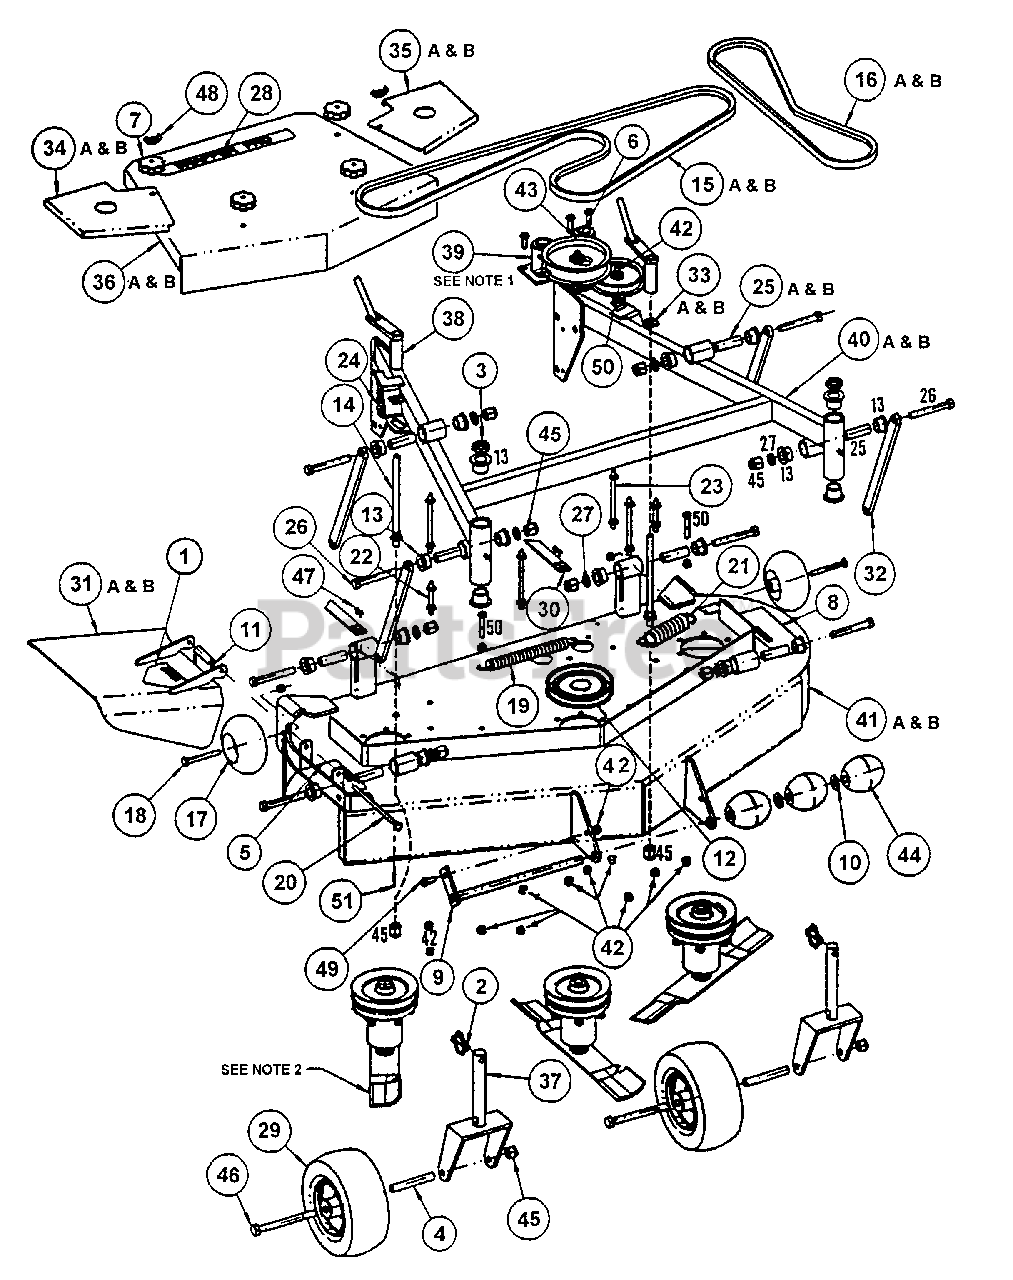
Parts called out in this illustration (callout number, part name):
1	DECAL, Warning (CPSC Cut Finger)
2	PIN, 7/16" HD Lynch
3	SPACER, 1" x 1 3/8 x .30" (PM)
4	SLEEVE/SPACER, Axle
5	DECAL, Warning
6	BUSHING, Caster
7	KNOB, Hood
8	DECAL, Caution- Operator Instruction
9	PIVOT, Roller Pin (Weldment)
10	WASHER, 5/8 Flat
11	SPRING, Chute
12	PULLEY, Driven 5-3/4 O.D.
13	BUSHING, Suspension
14	STUD, Lift
15A	V-Belt, Secondary 48" (113" Long)
15B	V-Belt, Secondary 52" (120" Long)
16A	V-BELT, Primary 48" (66" Long)
16B	V-BELT, Primary 52" (69" Long)
17	WHEEL, Gage
18	BOLT, Gage Wheel
19	SPRING, Extension Primary Idler
20	PIN, Chute Hinge
21	SPRING, Idler
22	STANDOFF, 2 Long
23	STANDOFF, 4-1/2" Long
24	DECAL, Height-of-Cut
25	SLEEVE, Suspension (48")
25	SLEEVE, Suspension (52")
26	BOLT, 1/2-13 x 3-3/4, Grade 5
27	WASHER, 1/2" Flat
28	DECAL, Snapper Pro
29	ASSEMBLY, Wheel/Tire
30	POINTER, Height-of-Cut
31A	DEFLECTOR, Chute 48"
31B	DEFLECTOR, Chute 52"
32	ARM, Suspension 12" (48" & 52")
33A	WASHER, Lift (48")
33B	WASHER, Lift (52")
34A	COVER, Right 48"
34B	COVER, Right 52"
35A	COVER, Left 48"
35B	COVER, Left 52"
36A	COVER, Center 48"
36B	COVER, Center 52"
37	CASTER Weldment
38	ASSEMBLY, Crank
39	ASSEMBLY, Idler 3-Spindle Dk.
40A	ASSEMBLY, Frame 48"
40B	ASSEMBLY, Frame 52"
41A	ASSEMBLY, Deck 48"
41B	ASSEMBLY, Deck 52"
42	NUT, 3/8-16 HEX NYLON LOCK
43	FITTING, Lube 1/4-28 Straight
44	ROLLER, Low Density Polyethylene
45	NUT, 1/2-13 Nyloc
46	BOLT, 1/2-13 X 5-1/2" GD5 YZ
47	SCREW, 1/4-20 x 3/8" H.W.S.T.
48	WING NUT, 5/16-18
49	BOLT, 3/8-16 X 1" GD5 CZ
50	BOLT, 3/8-16 X 2, GD5, CZ
51	PIN, 3/32 x 1" Cotter
